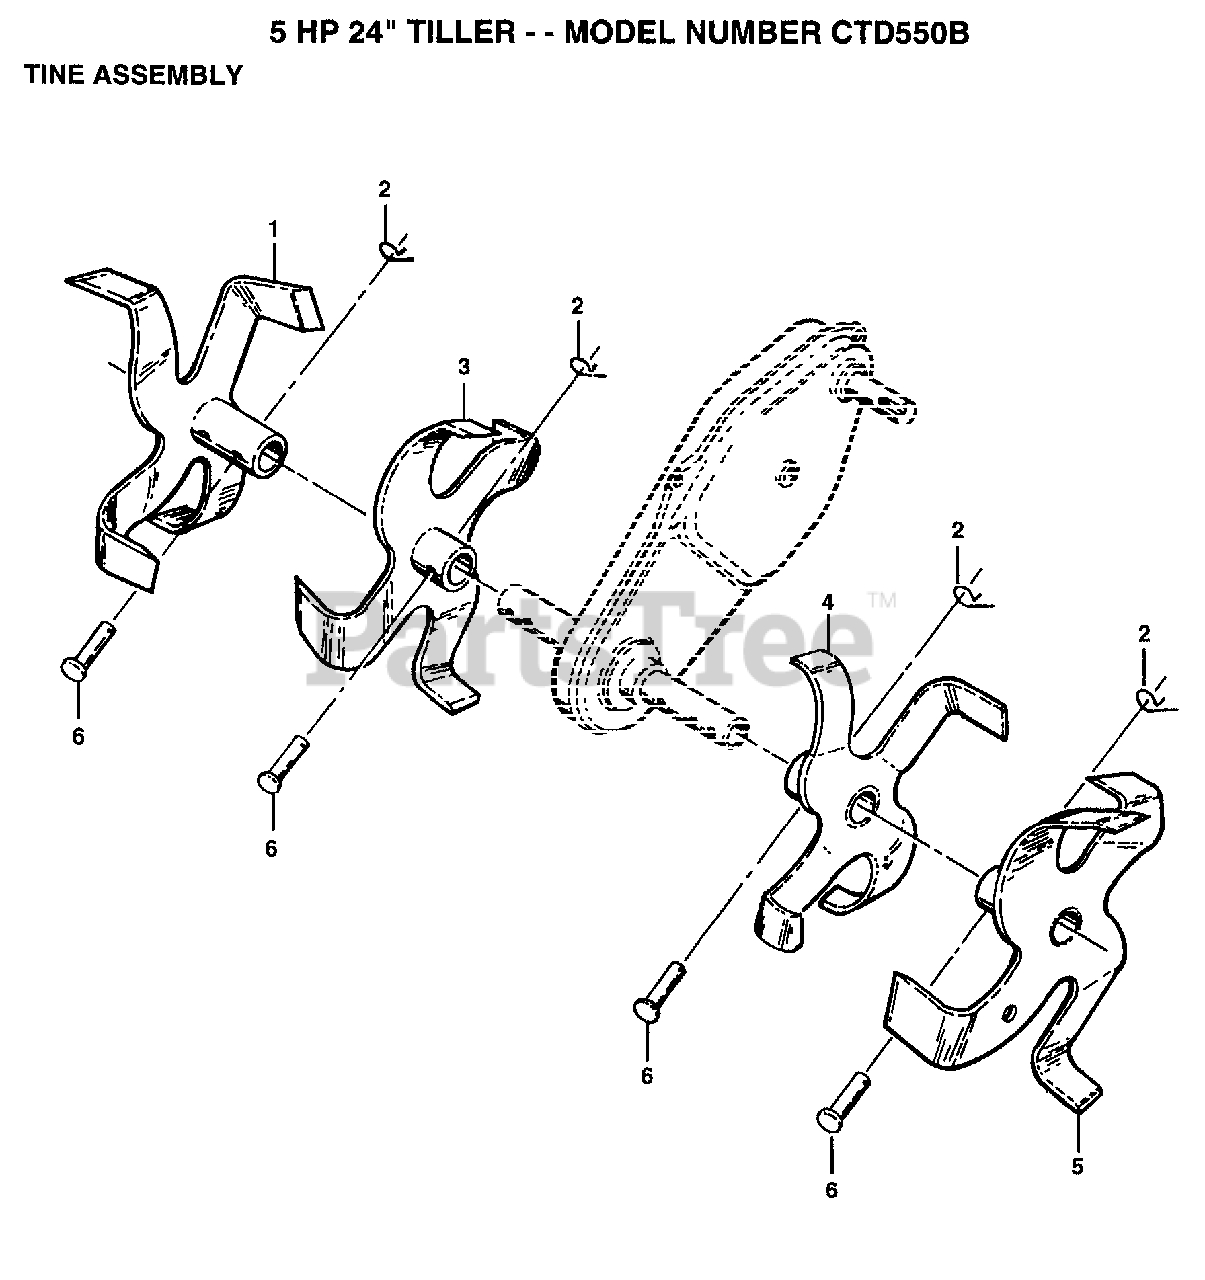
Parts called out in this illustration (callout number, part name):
1	TINE OUTER RH T
2	RETAINER.SPRING
4	TINE.INNER.LH
5	TINE.OUTER.LH.T
6	RIVET.PAN HD.1.75
